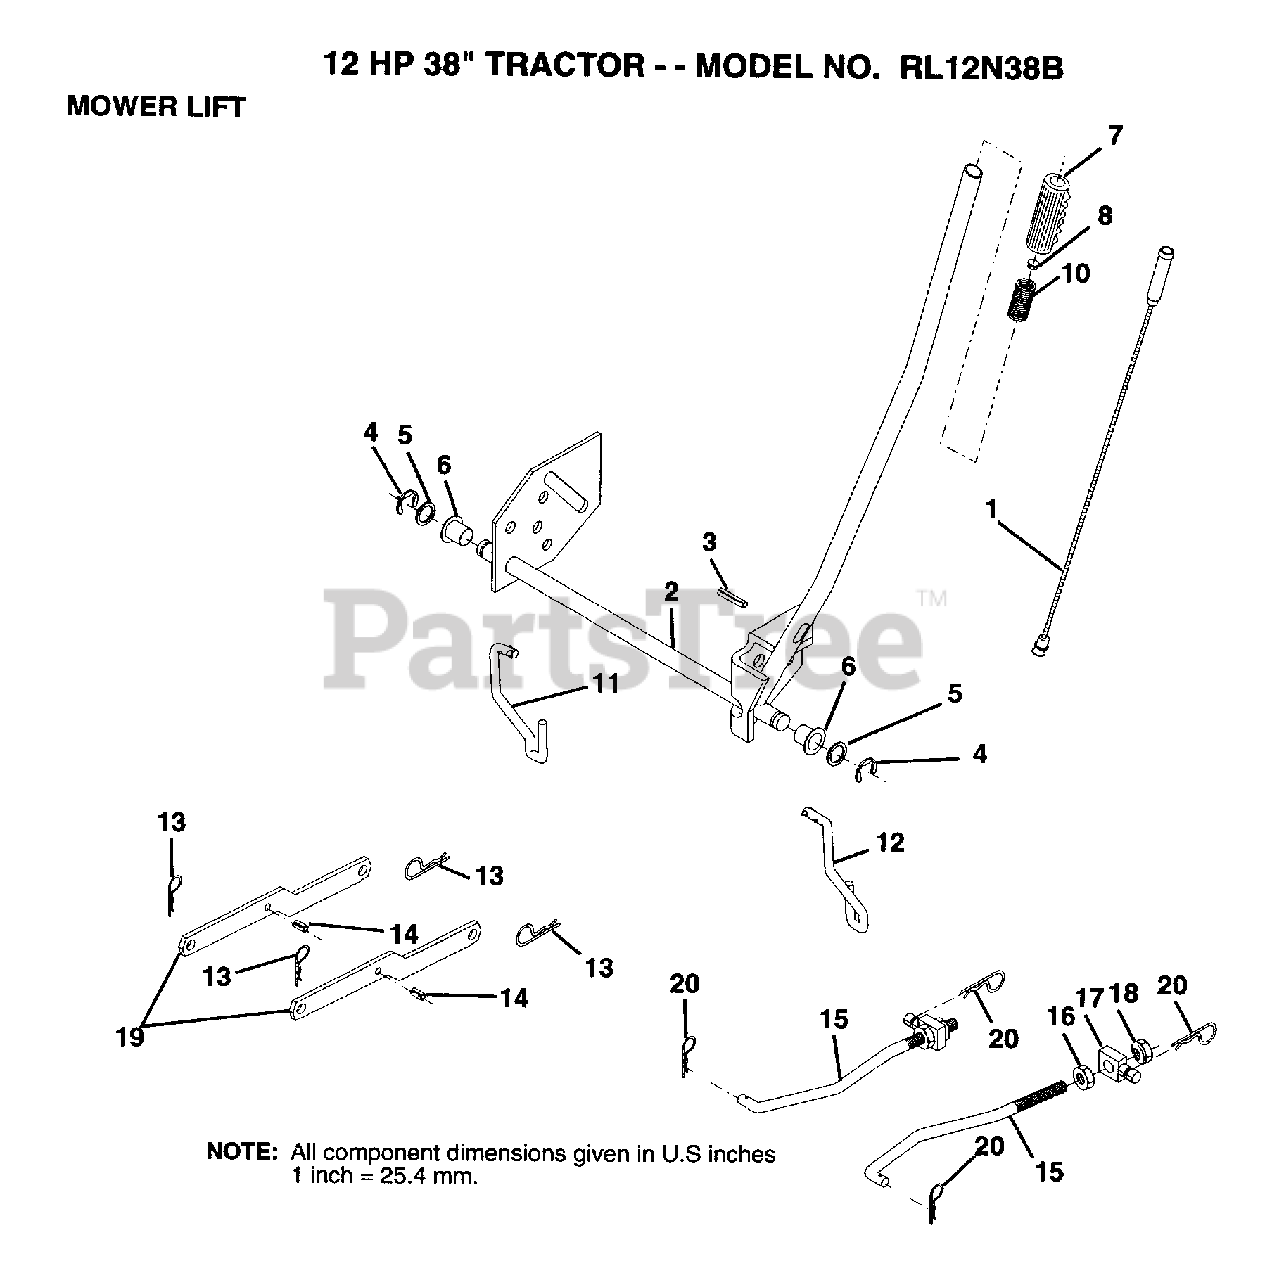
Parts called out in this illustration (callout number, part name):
1	WIRE ASM
3	PIN-GROOVE LT
5	WASHER
6	NYLON BEARING
7	GRIP
11	LINK LIFT LH
12	LIFT LINK RH
14	"PIN,SPRING"
15	LINK.FRONT
16	NUT
17	TRUNION
18	NUT.LK.W/WSH.1/2.
20	RETAINER.SPRING
